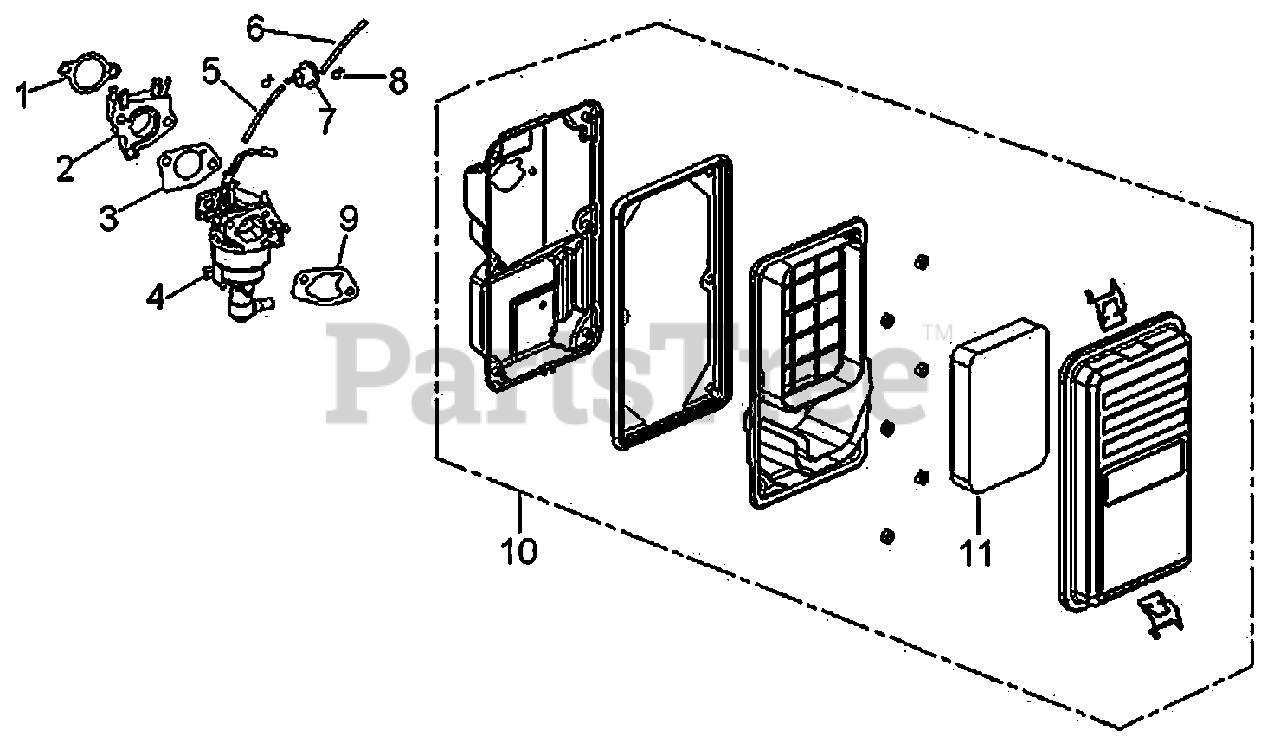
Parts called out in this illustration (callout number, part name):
1	GASKET, CARBURETOR
2	SPACER, CARBURETOR
3	GASKET, CARBURETOR
4	CARBURETOR ASSY.
5	TUBE, FUEL
6	TUBE, FUEL
9	GASKET, CARBURETOR
10	AIR CLEANER
11	ELEMENENT, AIR CLEANER
